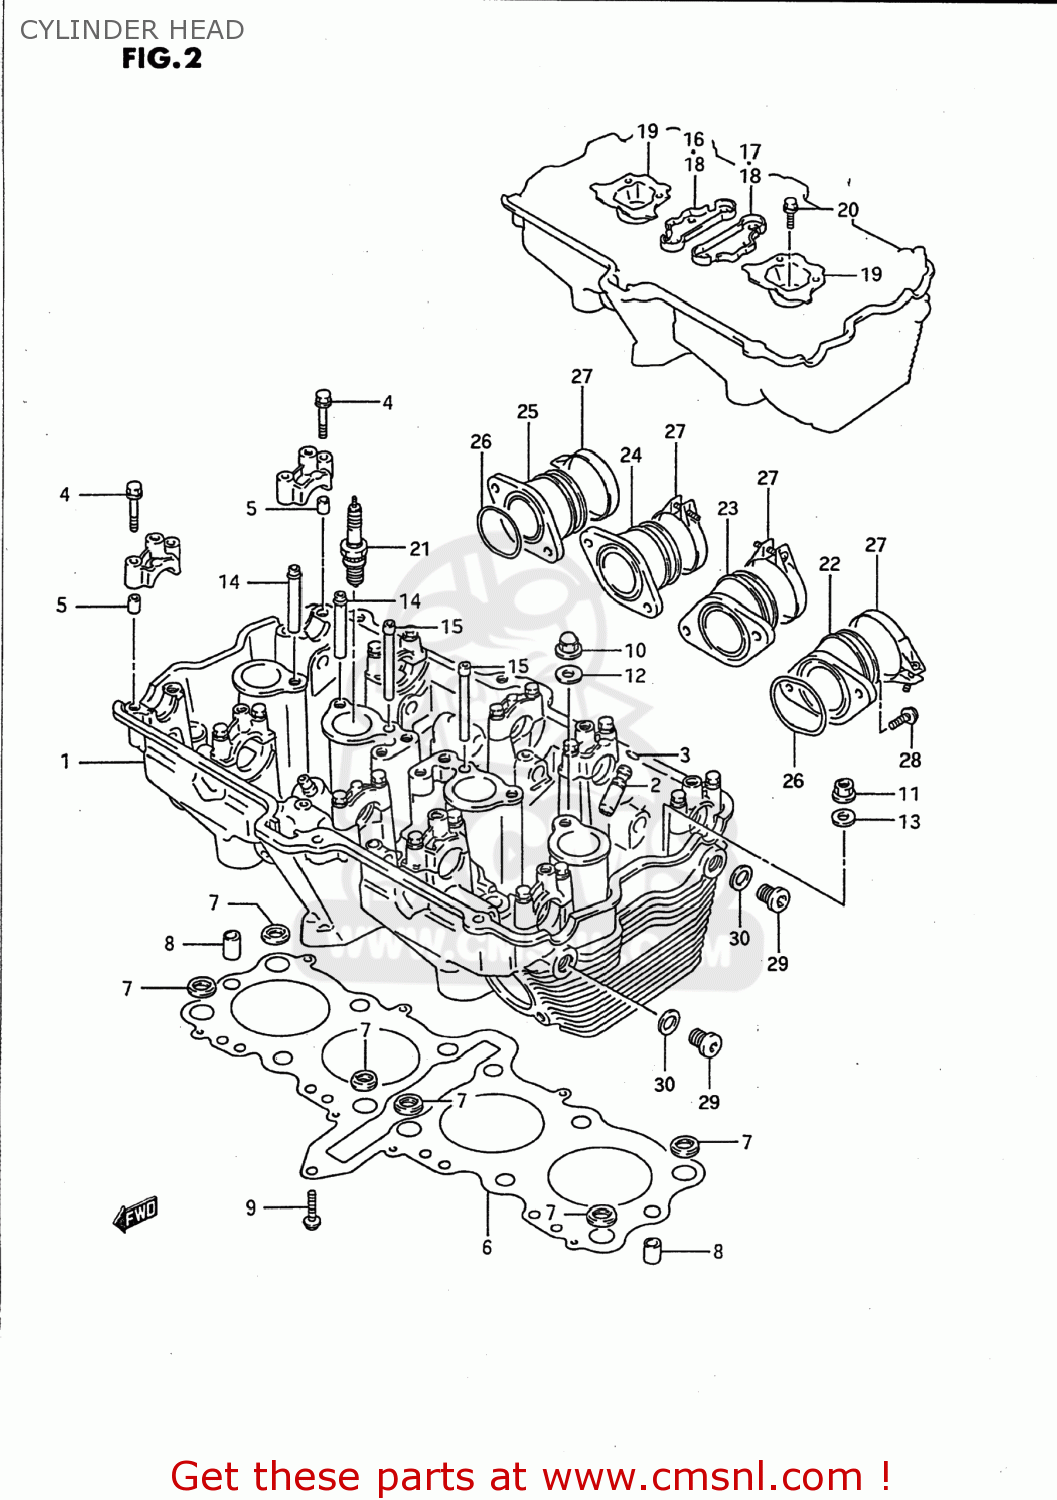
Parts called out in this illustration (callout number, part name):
1	HEAD ASSEMBLY,CYLINDER
2	GUIDE,VALVE
3	RING,SNAP
4	BOLT(6X39)
5	PIN(6.2X8X11)
6	GASKET,CYLINDER HEAD (NAS)
7	O RING,HEAD GASKET
8	PIN
9	BOLT
10	NUT
11	NUT
12	GASKET(10.2X20X2).3 (NAS)
13	WASHER (10.5X22X2.3)
14	PIPE,OIL NO.1
15	PIPE,OIL NO.3
16	PLATE
17	PLATE
18	PLATE,OIL PIPE NO.1
19	PLATE,OIL PIPE NO.2
20	BOLT
21	PLUG,SPARK(JR9C)
22	PIPE ASSEMBLY,INTAKE
23	PIPE ASSEMBLY,INTAKE
24	PIPE ASSEMBLY,INTAKE
25	PIPE ASSEMBLY,INTAKE
26	O RING(D:2.4,ID:39.7)
27	CLAMP
28	SCREW
29	PLUG
30	GASKET(13.8X18.8X4.8) (NAS)
